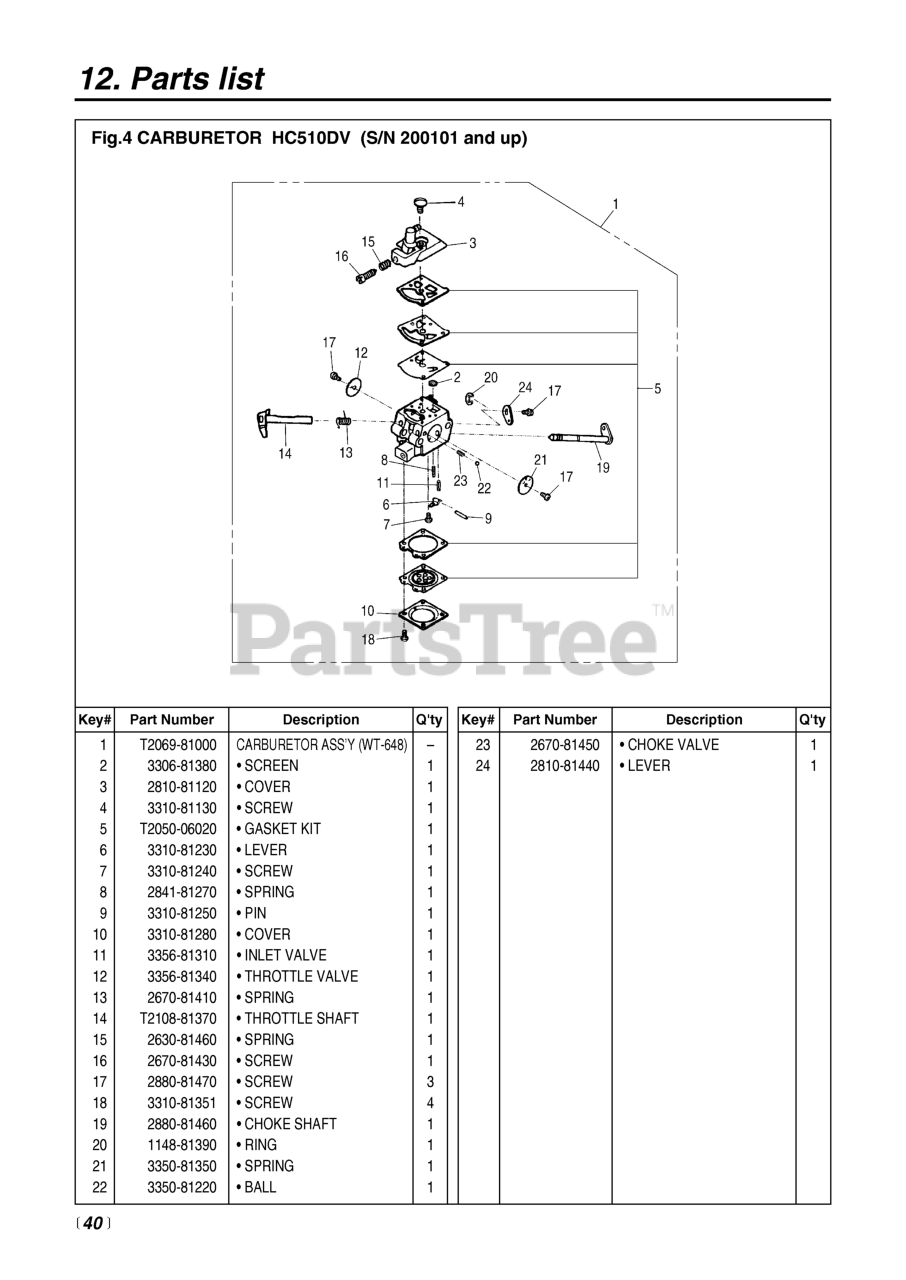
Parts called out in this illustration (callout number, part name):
1	CARBURETOR ASSY. (HC510DV)
3	COVER ASSEMBLY
5	GASKET KIT
6	LEVER
8	SPRING (USE 2867-81270)
9	PIN, METERING LEVER
11	VALVE, INLET
12	VALVE, THROTTLE
13	SPRING, RETURN
14	SHAFT ASSEMBLY, THROTTLE
15	SPRING, IDLE
17	SCREW (RPLS 3310-81360)
18	SCREW ASSEMBLY
19	SHAFT, CHOKE
21	SPRING
22	BALL, FRICTION
23	VALVE, CHOKE
